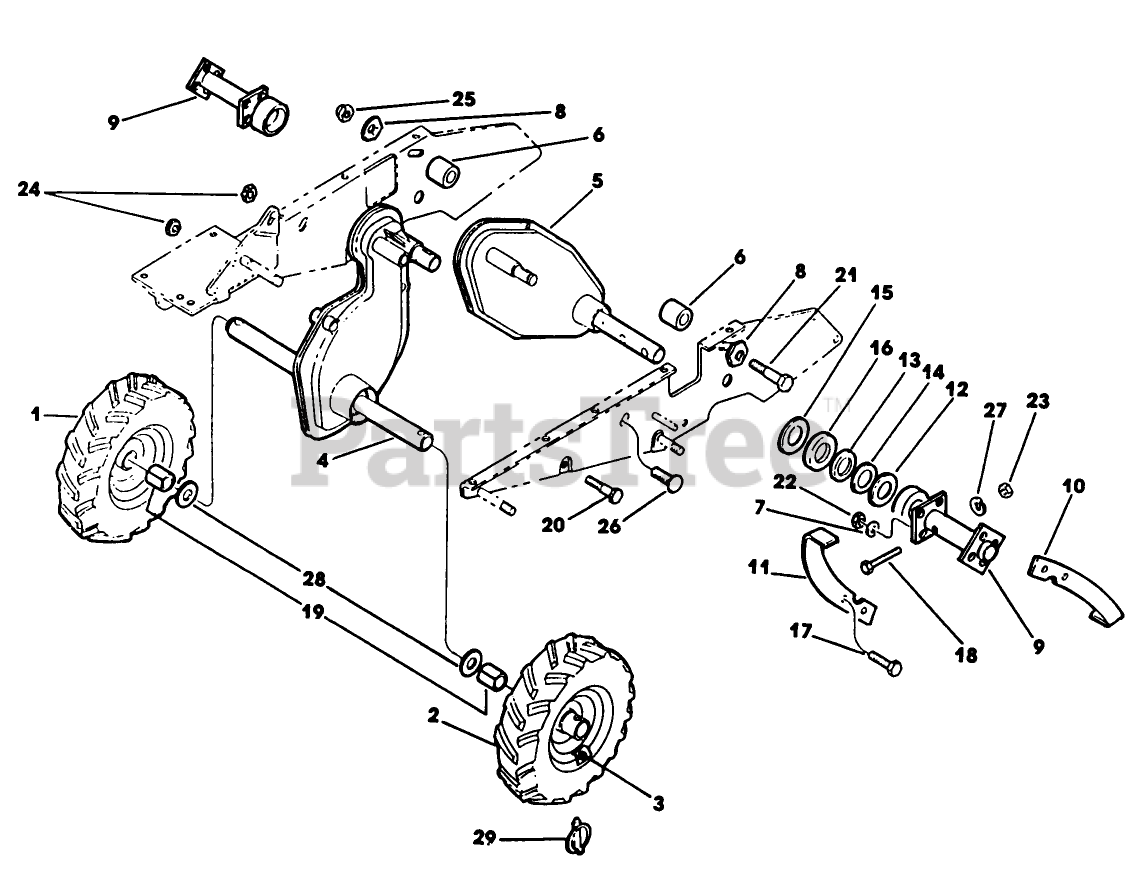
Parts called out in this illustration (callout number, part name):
10	TINE - RH
11	TINE - LH
13	SEAL-FELT
14	WASHER
15	WASHER BACK-UP
16	SEAL - FELT
22	HEX NUT
25	NUT
27	WASHER
28	WASHER
29	KILK PIN
